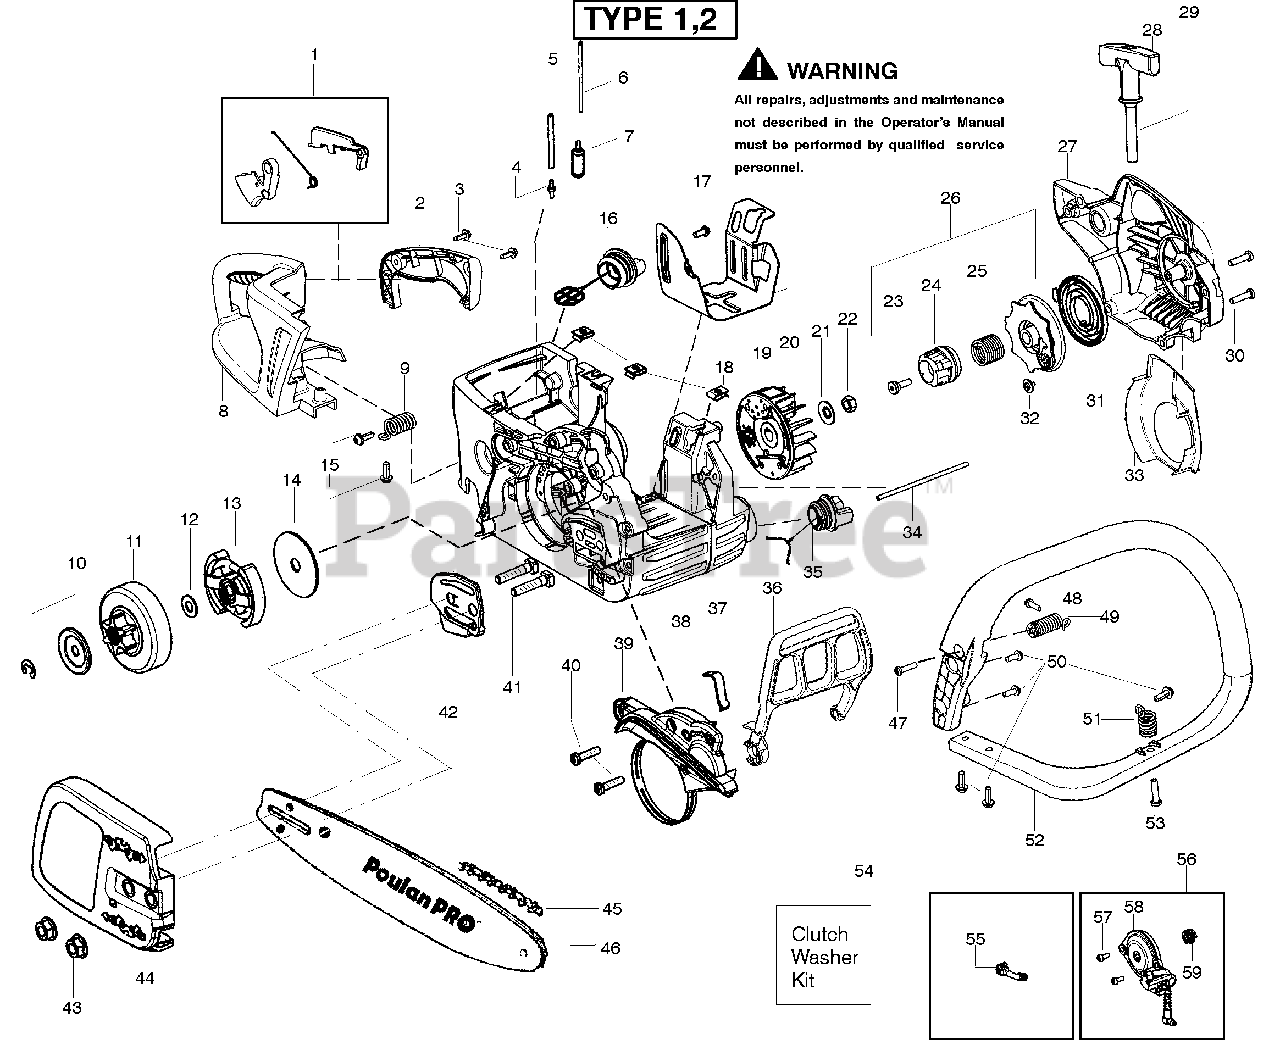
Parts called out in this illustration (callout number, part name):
1	Kit-Trigger/Lockout
2	Cover-Handle
4	Fitting-Fuel line
5	Kit-Fuel Line (Large)
6	Kit-Fuel Line (Small)
7	Assy-Fuel Pick Up
8	Handle-Rear
9	Spring-Rear Isolator
10	Kit-Clutch Washer
11	Assy-Clutch Drum 3/8"
12	Kit-Clutch Washer
13	Assy-Clutch
14	Washer-Large Clutch
16	Assy-Fuel Cap w/ret
18	Nut-"U" type speed
19	Assy-Flywheel
20	Shield-Heat
21	Washer-Flywheel
22	Nut-Flywheel
23	Screw-Shoulder
24	Starter Hub-EPS
25	Spring-EPS
26	Kit- EPS Starter Pulley
27	Housing-Fan
28	Handle-Starter
29	Kit-Rope
31	Spring-Starter
34	Assy-Oil Vent
35	Assy-Oil Cap w/ret.
36	Handguard
37	Spring-Handguard
38	Assy-Chassis
39	Kit-Chainbrake
41	Bolt-Bar
42	Plate-Bar
44	Cover-Clutch
45	Accy-18" Chain
46	Accy-18" Bar
49	Assy-Rear Iso. Spring
51	Assy-Front Iso. Spring
52	Handle-Front
54	Kit-Clutch Washer
55	Assy-Oil Pick Up
56	Kit-Oil Pump
58	Assy-Oil Pump
59	Gear-Worm
